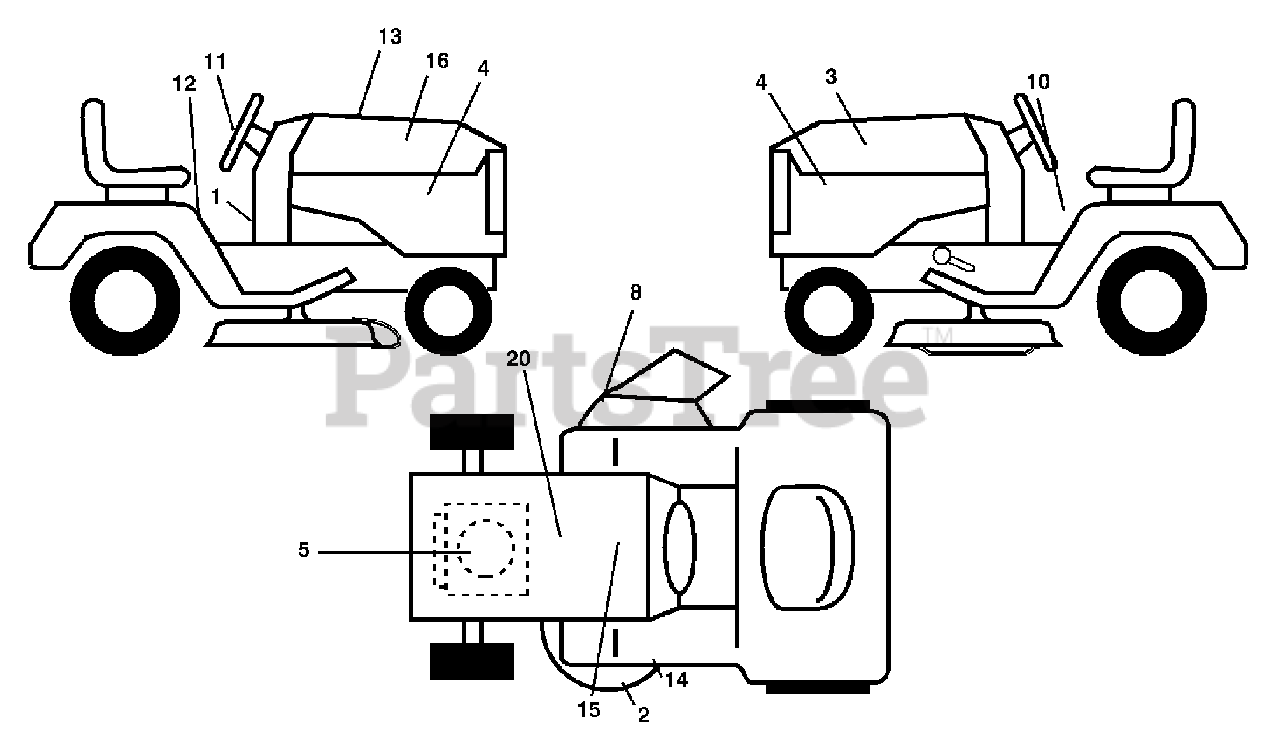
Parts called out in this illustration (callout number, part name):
1	Decal Dash
2	Decal Heavy Duty
3	Decal Hood LH
4	Decal Side Panel
5	Decal Engine
8	Decal Warning Mower
10	Decal Fender Danger EIF
11	Decal Ins Strg Whl
12	Decal Fender Oper
13	Decal Hood Gust Resp.
14	Decal V-Belt Schematic
15	Decal Replacement
16	Decal Hood Rh
20	Decal Bat Dan/Psn
20	Decal By Pass
